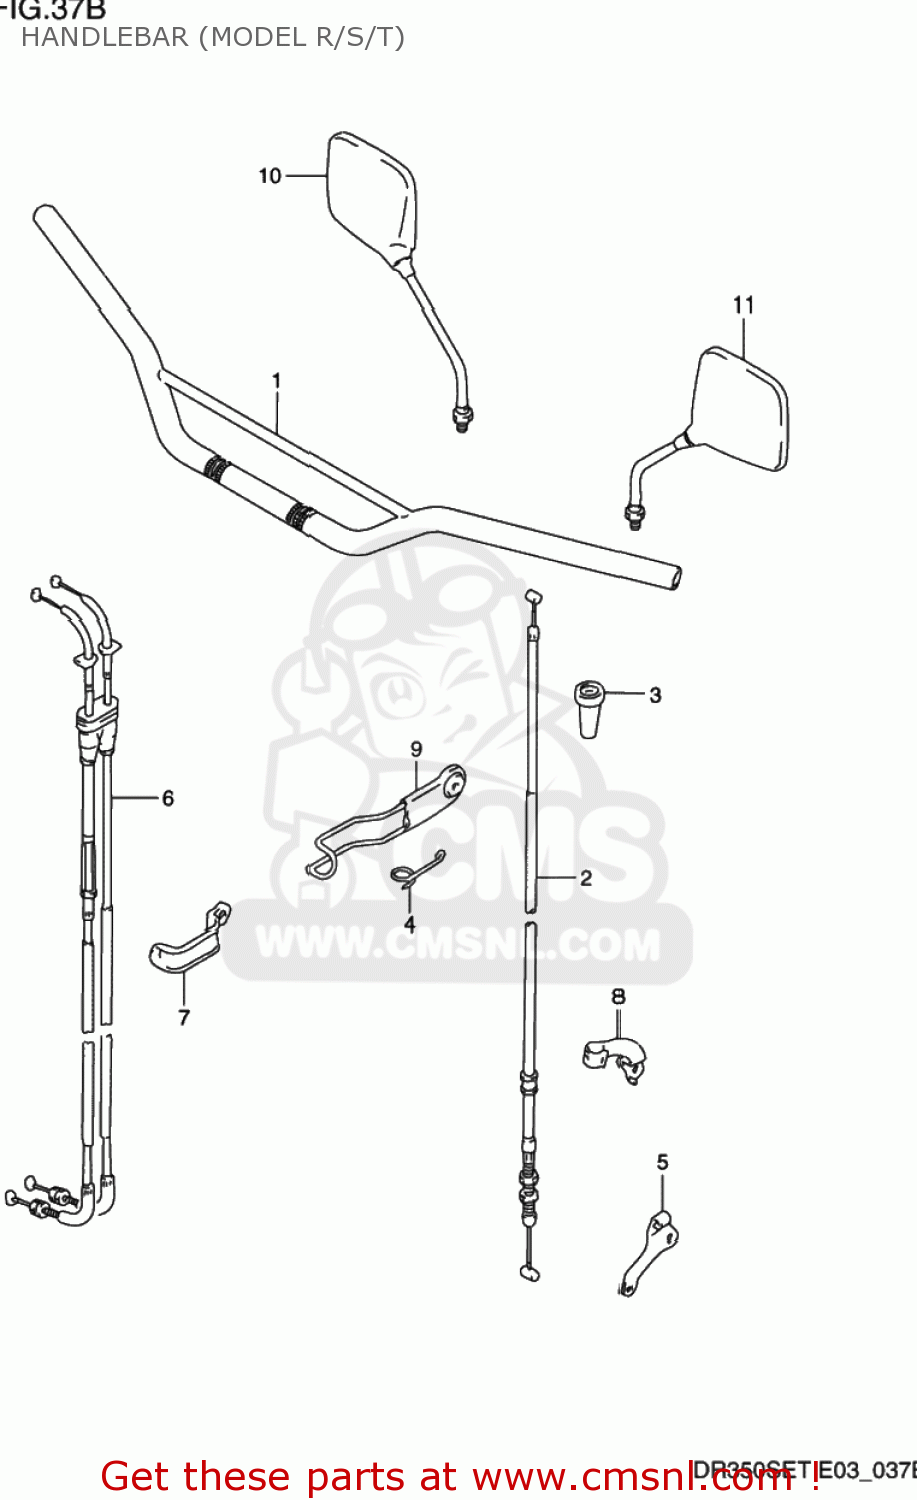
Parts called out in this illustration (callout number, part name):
1	HANDLEBAR
2	CABLE ASSY,CLUTCH
3	BOOT,CLUTCH CABLE
4	GUIDE,CLUTCH CABLE
5	STOPPER,CLUTCH CABLE
6	CABLE ASSY,THROTTLE
7	CLAMP
8	CLAMP,CLUTCH CABLE
9	GUIDE,CLUTCH CABLE
10	MIRROR ASSEMBLY,RIGHT
11	MIRROR ASSEMBLY,LEFT
